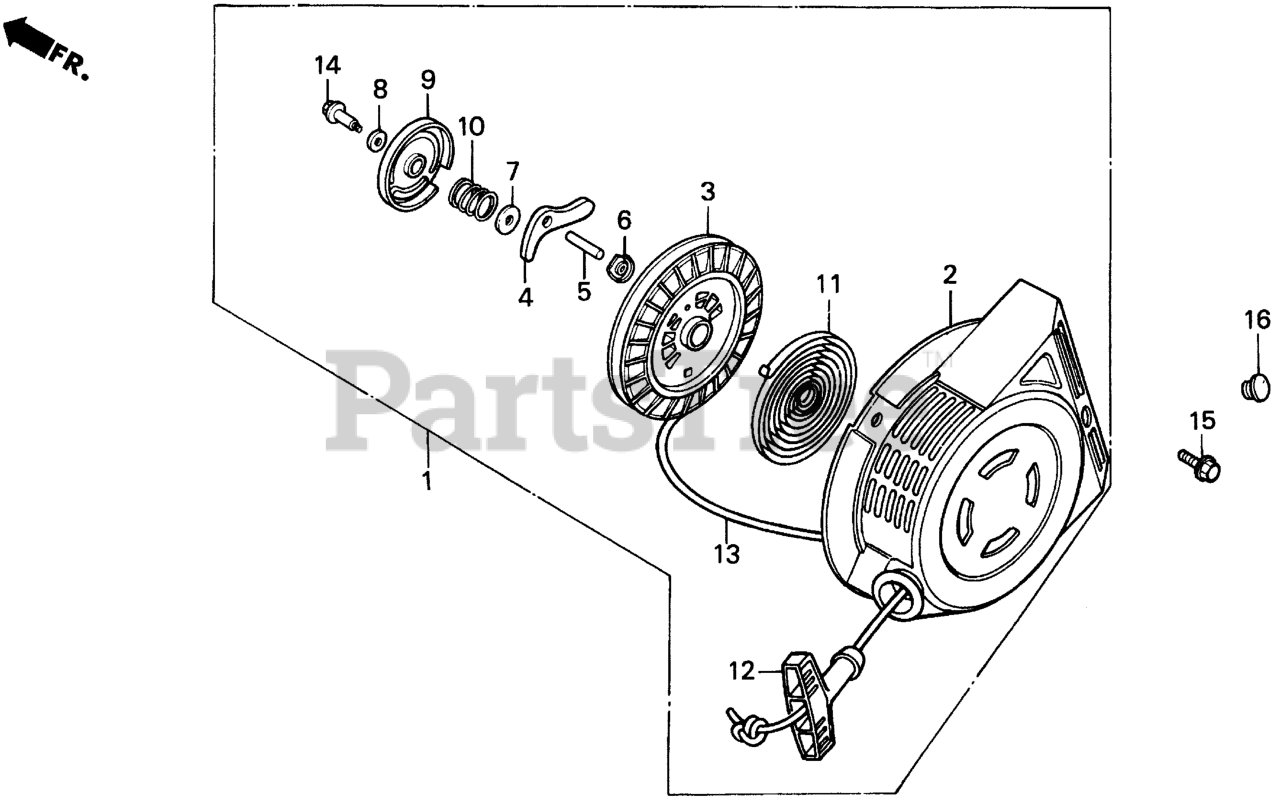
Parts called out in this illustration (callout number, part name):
1	STARTER ASSY., RECOIL
1	STARTER ASSY., RECOIL *R8* (BRIGHT RED)
2	CASE, RECOIL STARTER
2	CASE, STARTER *R8* (BRIGHT RED) (NOT AVAILABLE)
2	CASE, RECOIL STARTER *R8* (BRIGHT RED)
3	REEL, STARTER
4	RATCHET, STARTER
5	SHAFT, RATCHET
6	PLATE, GUIDE
7	PLATE A, FRICTION
8	PLATE B, FRICTION
9	COVER, REEL STARTER
10	SPRING, FRICTION
11	SPRING, RETURN
12	GRIP, STARTER
13	ROPE, RECOIL STARTER (#5X59") (NA USE ALT:08550-ZG921-11)
14	BOLT, REEL COVER
15	BOLT, FLANGE (6X8)
16	GROMMET B, CONTROL WIRE (16MM)
